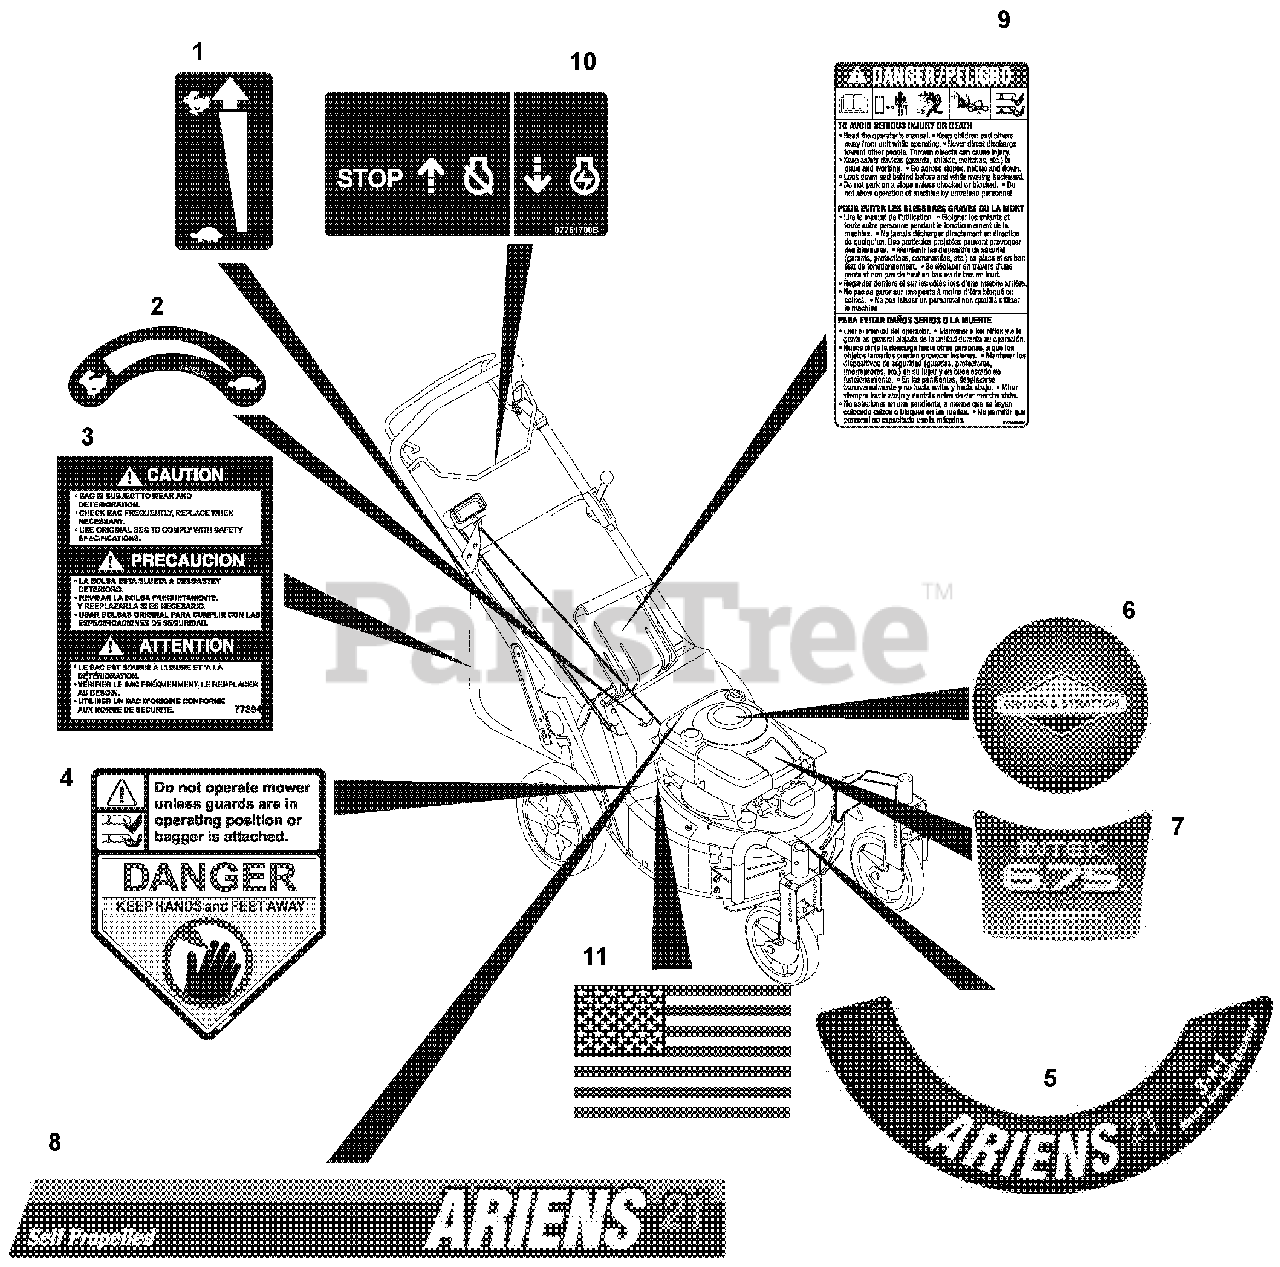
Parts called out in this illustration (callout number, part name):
1	DECAL-SPEED CONTROL
2	DECAL, TURTLE & RABBIT
3	LABEL - BAGGER 21"
4	DECAL, CPSC DANGER
5	DECAL, ARIENS DECK
5	DECAL, ARIENS DECK (PRO HONDA)
6	DECAL,BRIGGS & STRATTON RECOIL
7	DECAL, B&S INTEK 6.75HP
7	DECAL, BRIGGS QUANTUM 6.5
8	DECAL, DRIVE COVER SP
8	DECAL, DRIVE COVER SP PROF
9	DECAL, BILINGUAL DANGER
10	DECAL - ENGINE CONTROL
11	DECAL, AMERICAN FLAG
